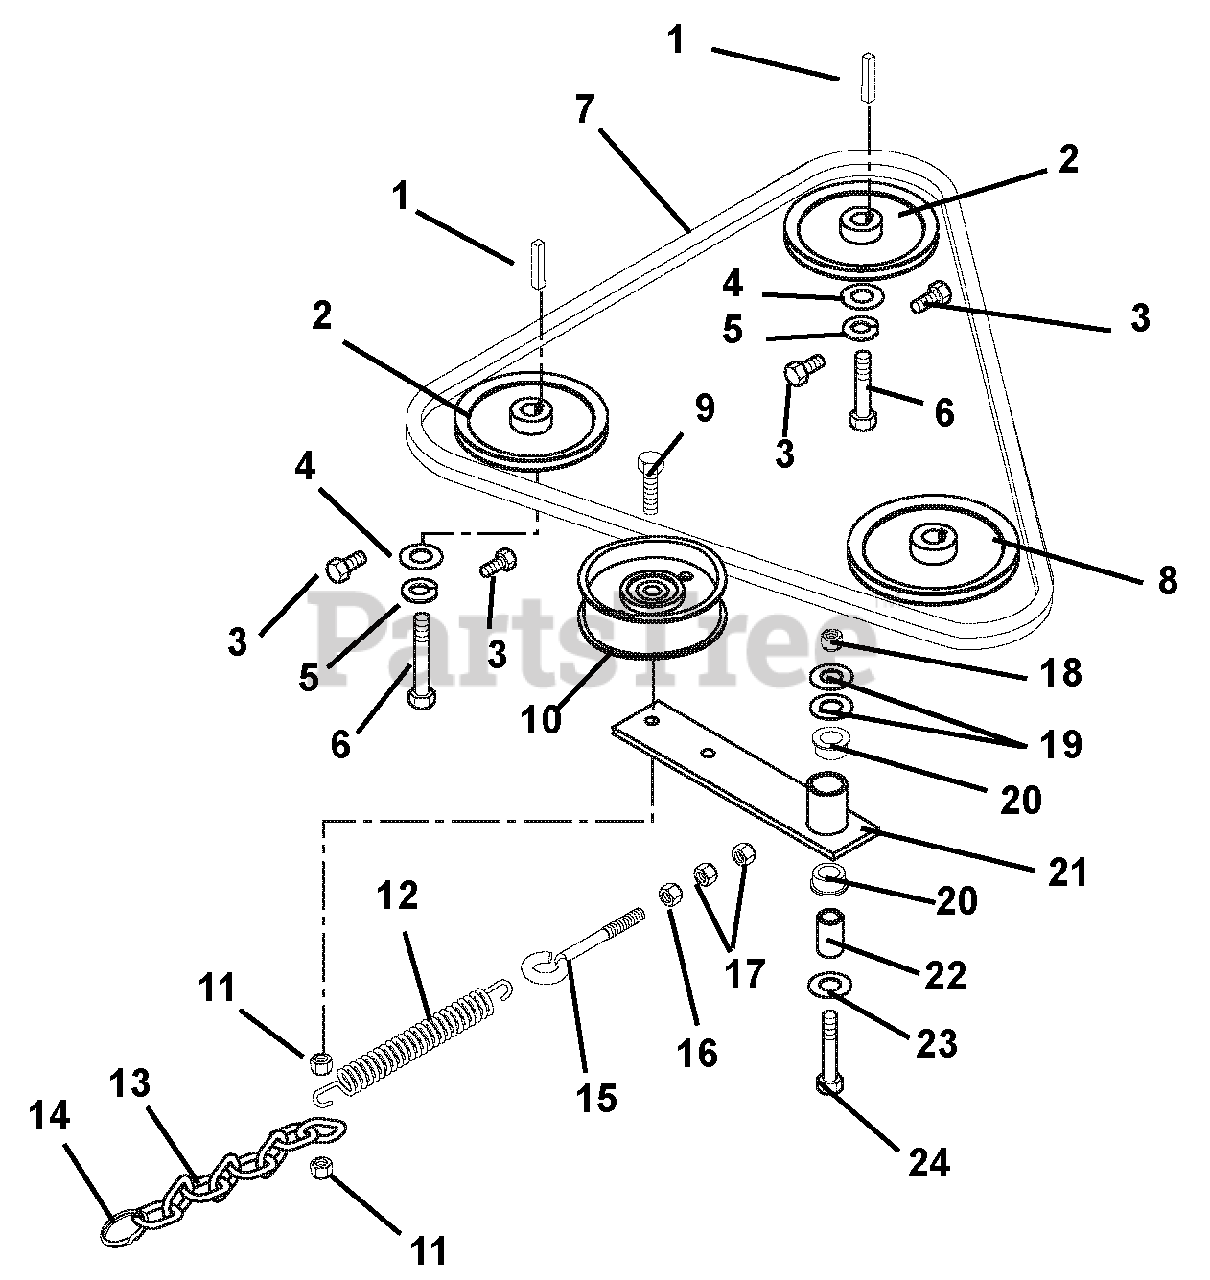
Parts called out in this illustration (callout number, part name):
1	Key-Straight 5MM x 25MM x 5MM
2	Sheave 4.0 x .199
3	Bolt-Hex .25-20 x .50 Grade 5
4	Washer-Flat-Steel .281 x 1.25 x .048
5	Washer-Locking .25 x .062 Regular
6	Bolt-Hex M6 x 1.0 x 12
7	Belt, Hydro Ground Drive
9	Bolt-Hex .38-16 x 2.00 Grade 5
10	Idler-Pulley Flat 3.25 x .625
11	Nut-Locking-Jam-Center .375-16
12	Spring, Extension
13	Chain, Link
14	Ring, Split .1 x 2
15	Bolt-Eye .375-16 x 2.50
16	Nut-Hex .38-16
17	Nut-Locking-Nylon .38-16
18	Nut-Locking-Nylon .50-13
19	Washer-Flat-Steel .531 x 1.06 x .095
20	Bushing-Flange Nylon .762 x 1.00 x .58 x 1.48
21	Weldment,Ground Drive Idler
22	Bushing,Spacer .56 x .745 x 2.04 Steel
23	Washer-Flat-Steel .531 x 1.06 x .095
24	Bolt-Hex .50-13 x 3.25 Grade 5
